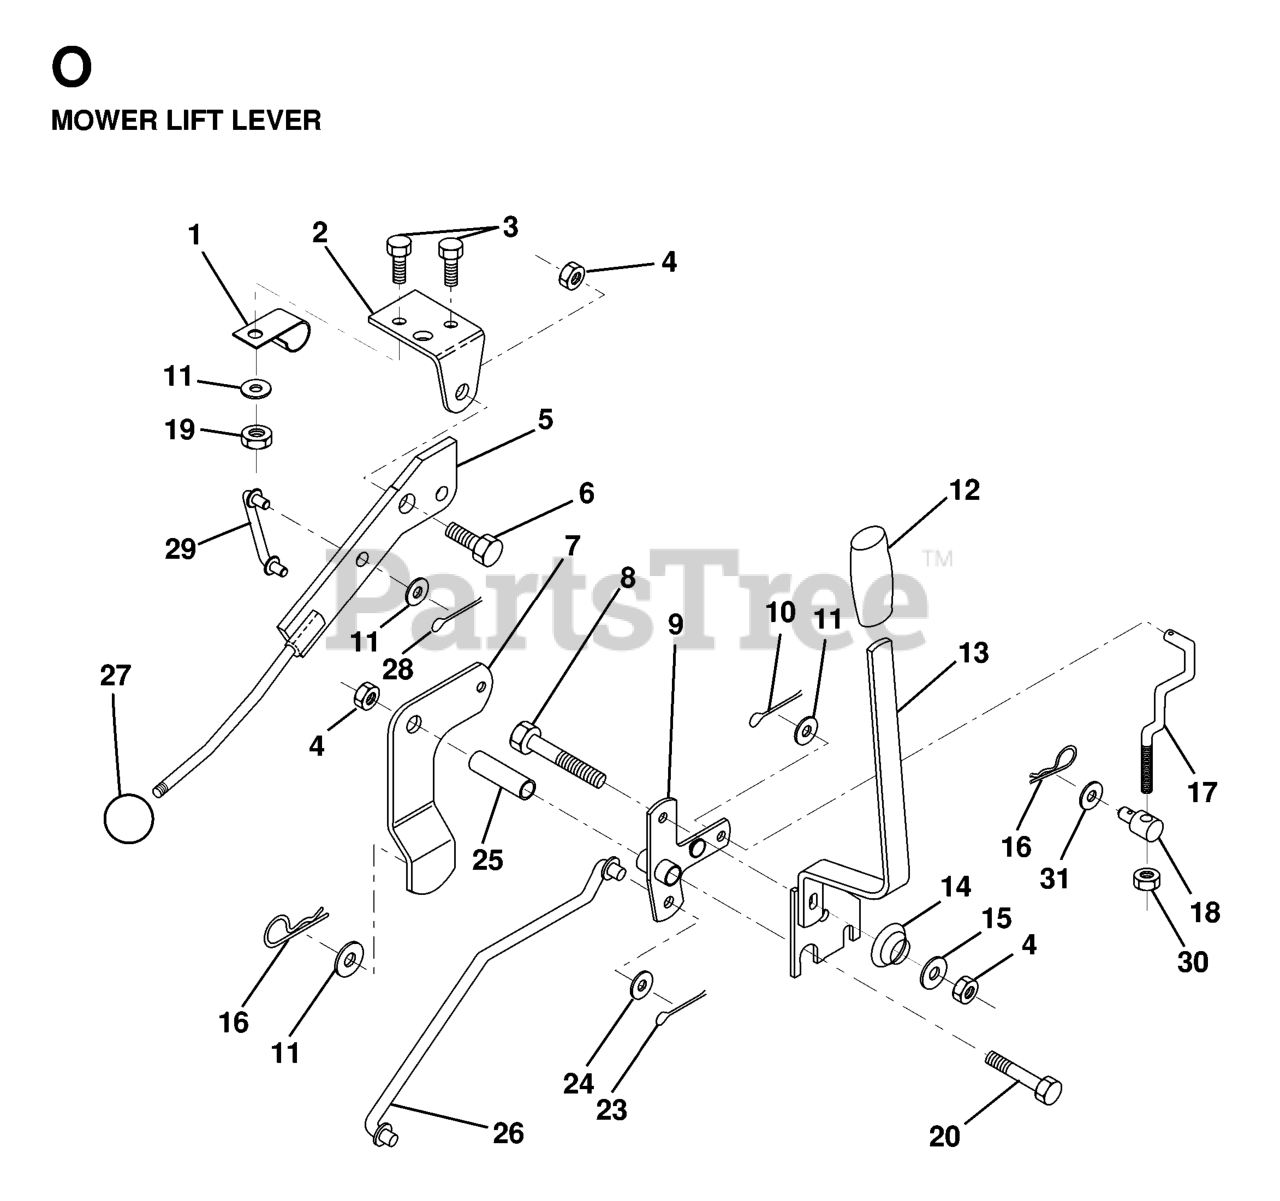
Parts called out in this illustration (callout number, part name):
1	CLIP,INSULATOR
2	BRKT CLUTCH
3	BOLT
5	CLUTCH LEVER
6	BOLT, SHOULDER LT
7	ASSEMBLY MOWER CLUTCH ARM
9	BELLCRANK,LIFT
10	COTTER PIN
11	WASHER
12	GRIP HANDLE
13	LIFT HANDLE ASSY
14	SPRING COMPRESSIO
15	WASHER T
16	SPRING TI
17	LINK LIFT FRT
18	TRUNNION.ADJUSTABLE.3/8-16
19	NUT.CROWNLOCK.1/4
23	PIN COTTER
24	WASHER GT
25	TUBE SPACER
28	COTTER PIN
29	LINK MOWER CLUTCH
30	NUT
31	WASHER
